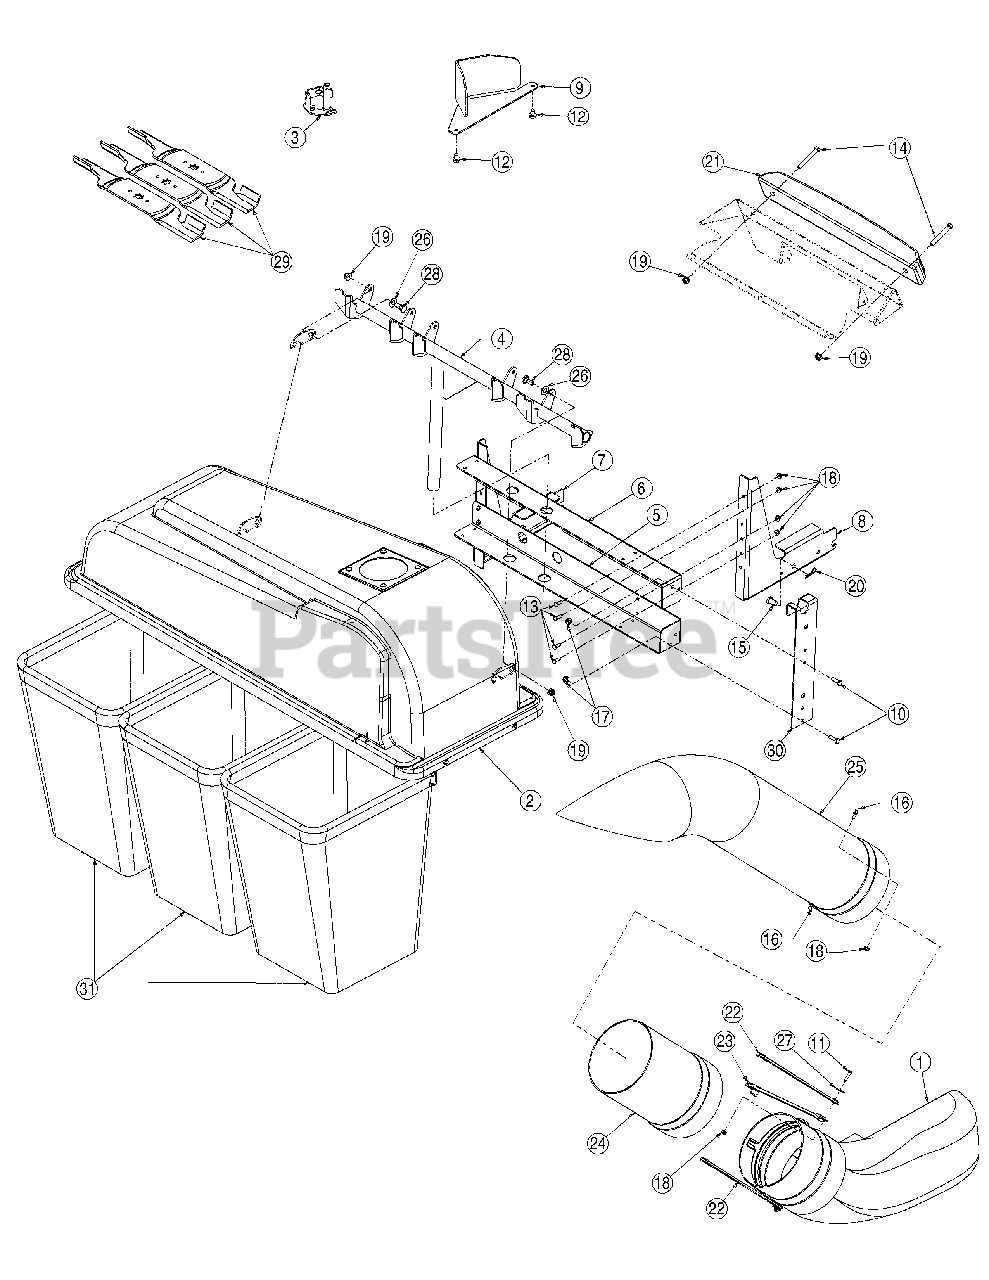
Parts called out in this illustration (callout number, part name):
1	Chute, Elbow
2	Grasscatcher Cover Assembly
8	Bracket, Catcher Support RH
10	Screw, Hex Cap, 5/16-18 x 1.0 Gr5
11	Screw, Hex Cap, 1/4-20 x 1.0 Gr5
12	Screw, Hex Wash. Hd. TT, 5/16-18 x 0.625
13	Screw, Hex Cap, 1/4-20 x 0.75 Gr5
14	Screw, Hex Cap, 3/8-16 x 2.75 Gr5
15	Pin, Clevis , .5 x .78
16	Pin, Grasscatcher 1/4-20
17	Nut, Hex Flange Insert Lock, 5/16-18
18	Nut, Hex Flange Insert Lock,1/4-20
19	Nut, Hex Flange Insert Lock, 3/8-16
20	Pin, Internal Cotter
21	Weight, Bagger
22	Chute Strap
23	Chute Strap
24	Tube, Extension, 8"
25	Tube, Catcher
26	Washer, Bell, .525 x 1.0 x .05
27	Washer, Flat, .265 x 1.0 x .03 HT
28	Shoulder Screw, .5 x .270: 3/8-16
29	Blade
31	Bag
